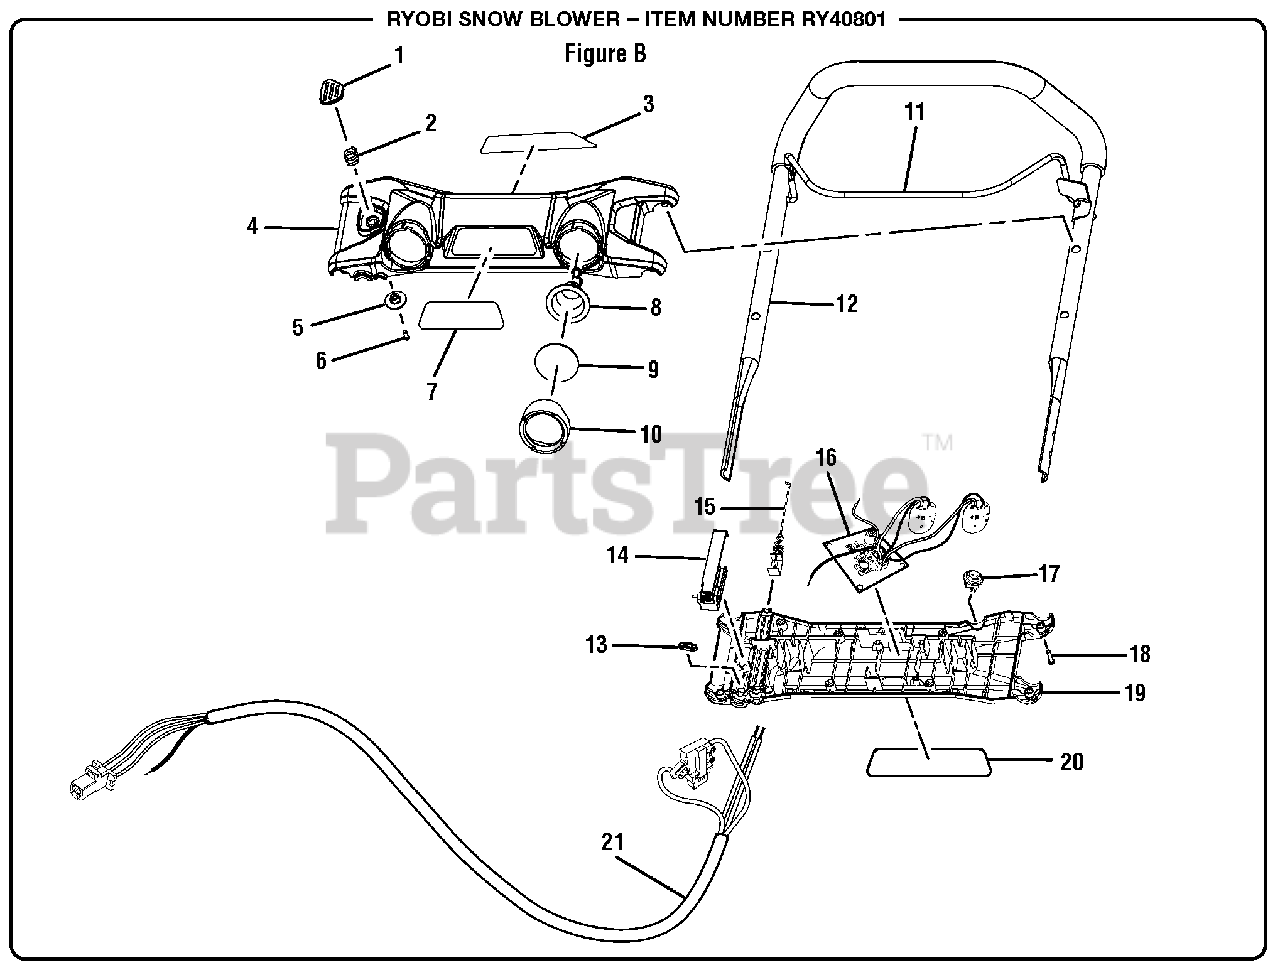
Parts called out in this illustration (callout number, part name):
3	Starting Instructions Label
4	Panel
6	Screw (M3.5 x 12 mm)
10	LED Housing
12	Upper Handle
14	Slider Assembly
15	Cable Assembly
16	LED Controller and Light Assembly
18	Screw (M4.2 x 16 mm)
19	Lower Panel
20	Warning and Data Label
21	Cord Assembly
